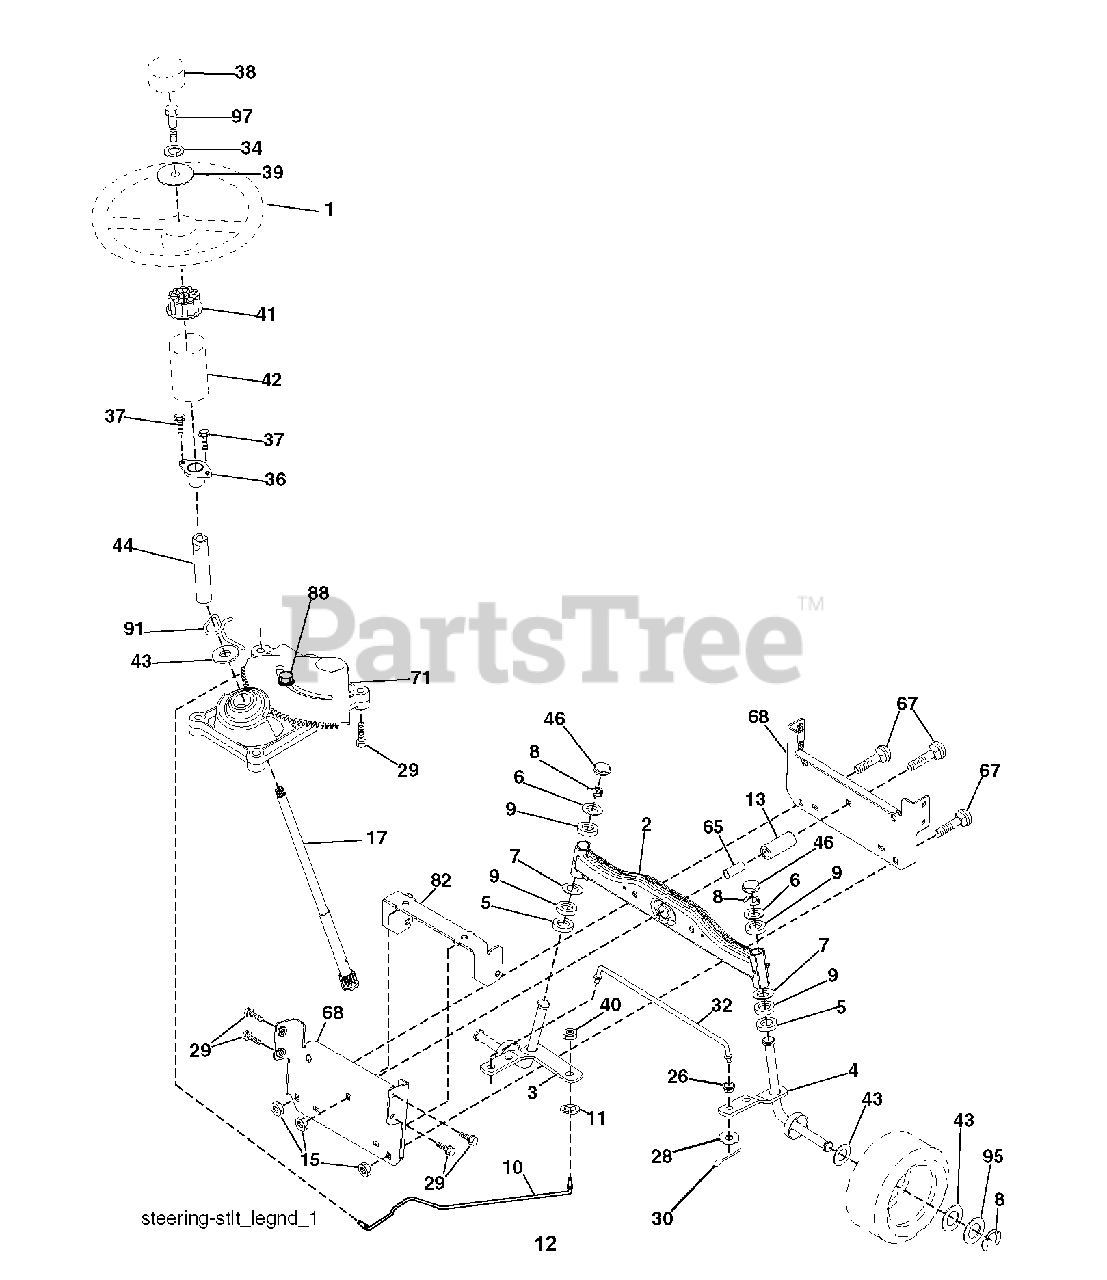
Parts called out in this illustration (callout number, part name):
2	AXLE.HALF.ASM.WELDED
3	SPINDLE.ASM.LH.15"TIRES
4	SPINDLE.ASM.RH.15"TIRES
8	RING CLIP
9	BRNG T
10	DRAGLINK.15".TIRES.2001
11	WASHER, LOCK 3/8
13	TUBE, PIVOT AXLE
15	NUT
17	SHAFT STEERING SPLINE
26	BUSHING.DRAGLINK
28	WASHER
29	SCREW, 3/8-16X3/4
30	COTTER PIN
32	ROD.TIE.WIRE.FORM
34	LOCKWASHER
36	BUSHING, STEERING
39	WASHER.11/32
40	NUT CROWNLOCK 3/8-24
41	ADAPTER, WHEEL STNG..
42	BOOT.STEERING.SHAFT.BLACK
44	SHAFT.EXTEN.STRG.SPLINE
46	CAP.SPINDLE
65	SPACER BRACE AXLE
67	BOLT CARRIAGE
68	BRACE.AXLE.15"TIRES
71	STEERING ASM
82	BRACKET.SUSP.CHASSIS.FRONT.15
88	BOLT, SHOULDER 7/16-20
91	CLIP.STEERING
95	WASHER.HARDENED
